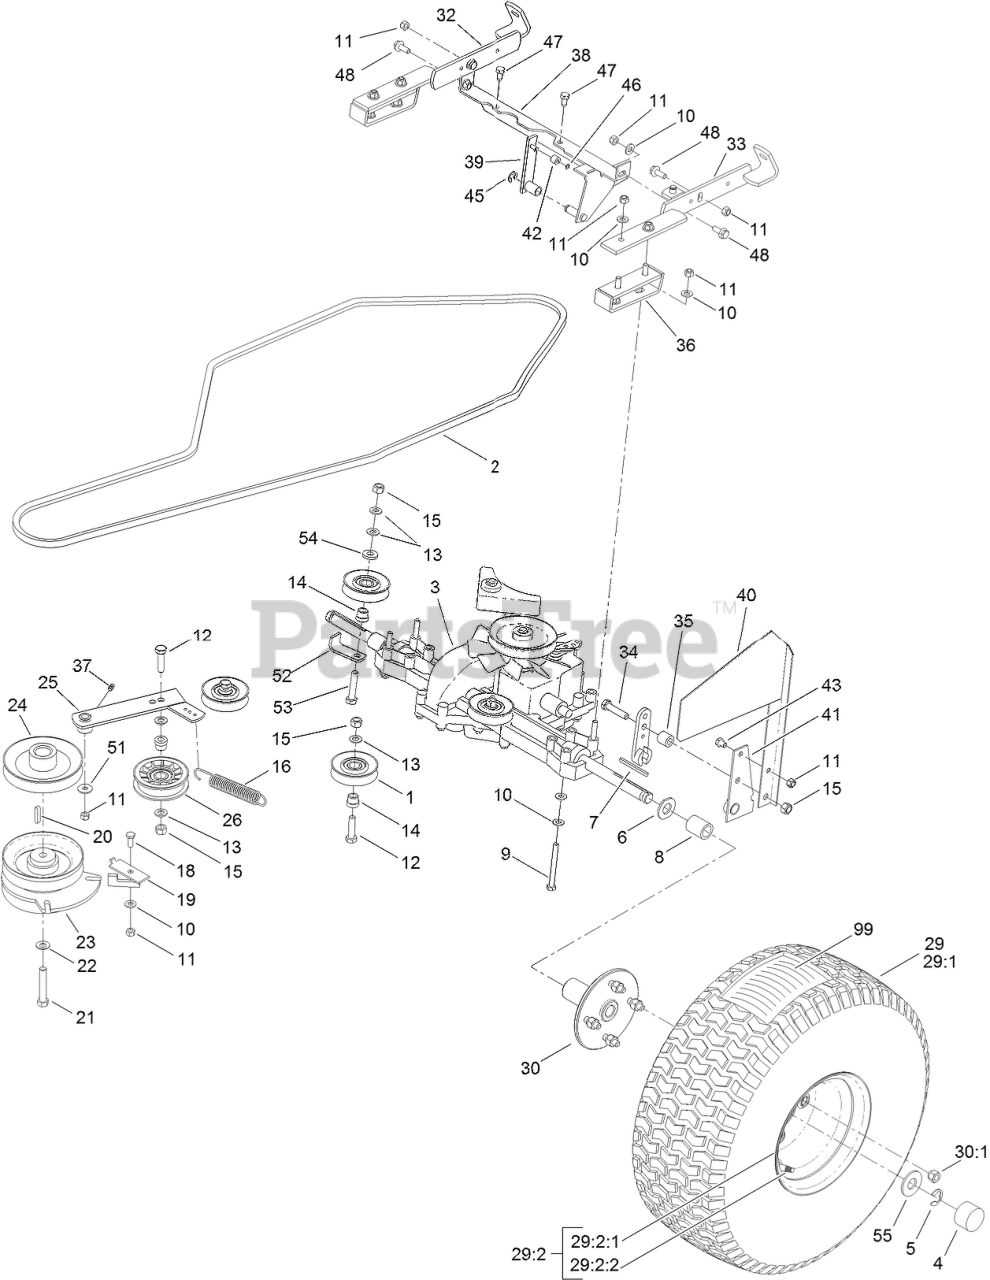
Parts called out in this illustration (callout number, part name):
1	PULLEY-IDLER
2	V-BELT-TRACTION
3	TRANSAXLE
4	CAP-HUB
5	CLIP-SPRING
6	WASHER
7	KEY-SQUARE
8	SPACER-AXLE
9	SCREW-HH
10	WASHER-PLAIN
11	NUT-LOCK, NI
12	SCREW-HH
13	WASHER-FLAT
14	BUSHING-IDLER
15	NUT-LOCK, NI
16	SPRING
18	SCREW-HH
19	RETAINER
20	KEY-SQUARE
21	SCREW-HH
22	WASHER-SPRING, BELLEVILLE
23	CLUTCH-ELECTRIC
24	PULLEY-ENGINE
25	ARM-IDLER
26	PULLEY-IDLER
29	TIRE AND WHEEL ASM
29:2	WHEEL ASM
29:2:1	RIM
29:2:2	Valve-Tire
30	HUB-WHEEL
30:1	NUT-LUG
32	Bracket-Right
33	Bracket-Left
34	SCREW-HH
35	SLEEVE
36	Plate-Reinforcing
37	FITTING-GREASE
38	Bar ASM
39	Arm-Switch
40	ARM-CONTROL, CRUISE
42	Roller
43	SCREW-HH
45	Stirrup
46	STIRRUP
47	SCREW-THREAD FORMING
48	SCREW-HEX
51	WASHER-PLAIN
52	RETAINER-BELT
53	SCREW-HH
54	WASHER-FLAT
55	WASHER
